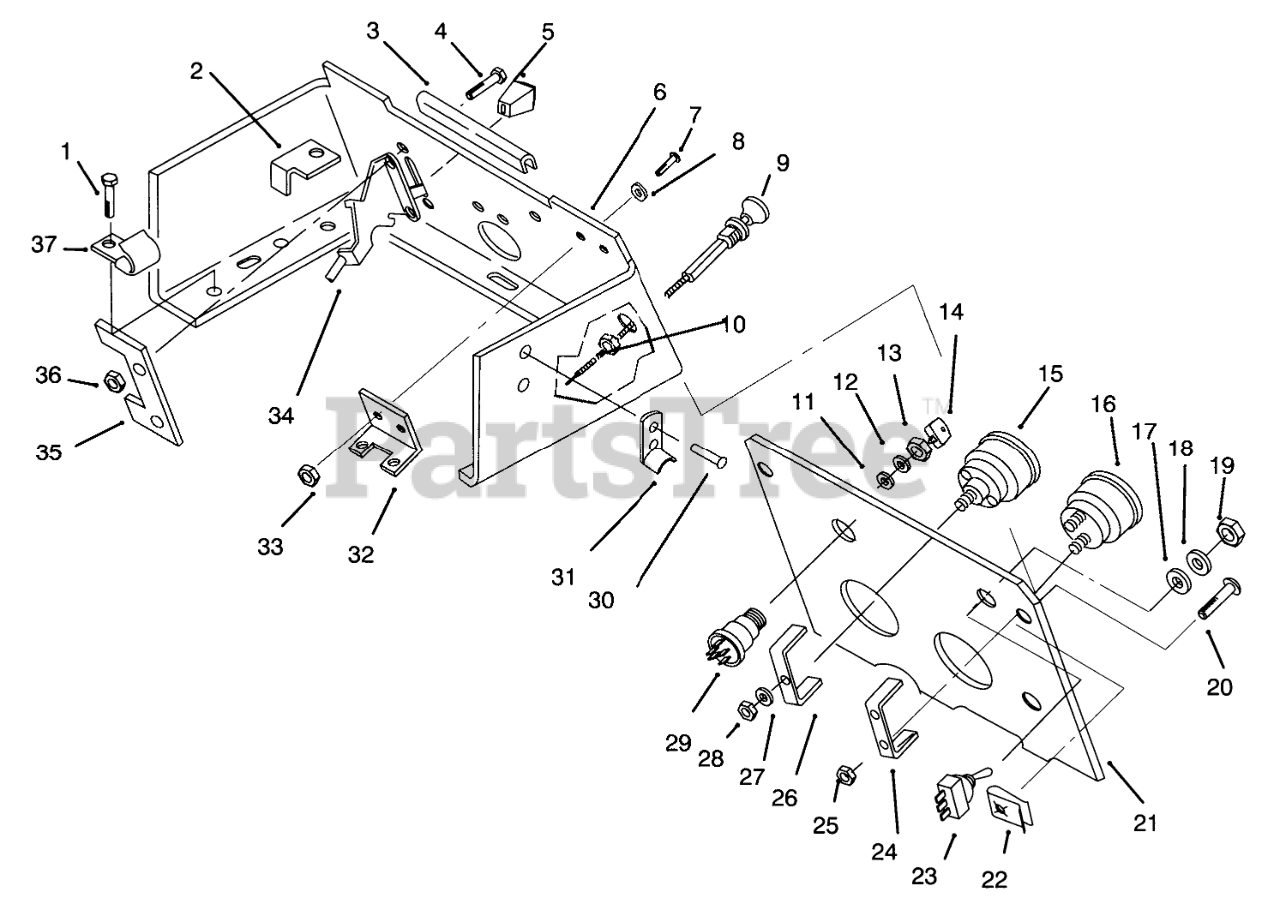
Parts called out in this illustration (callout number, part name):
1	SCREW
2	STOP-PTO
3	EDGING-CONSOLE
4	Screw
6	Console
7	SCREW
8	Washer-Lock
9	CONTROL CHOKE
10	NUT-HEX PALNUT
11	Washer
12	LOCKWASHER
14	KEY-IGNITION
15	Meter-Hour (Incl. Ref.# 27-28)
16	Meter-Volt (Incl. Ref.# 24-25)
17	Washer
18	TAB-WASHER
20	Screw
21	Plate-Hood Stand
22	CLIP
23	Switch-Light (Incl. Ref. #17-19)
24	CLAMP-MOUNTING
25	HEX NUT 10-32 E.S.
26	CLAMP-HOUR METER
27	WASHER-LOCK
28	NUT-HEX
29	Switch-Ignition (Incl. Ref.#11-13)
30	POPRIVET 1/8X 1/8 BK
31	KEEPER-LATCH
32	BRACKET
33	Nut
34	CONTROL-THROTTLE
35	Washer
36	Nut
37	J-CLIP
